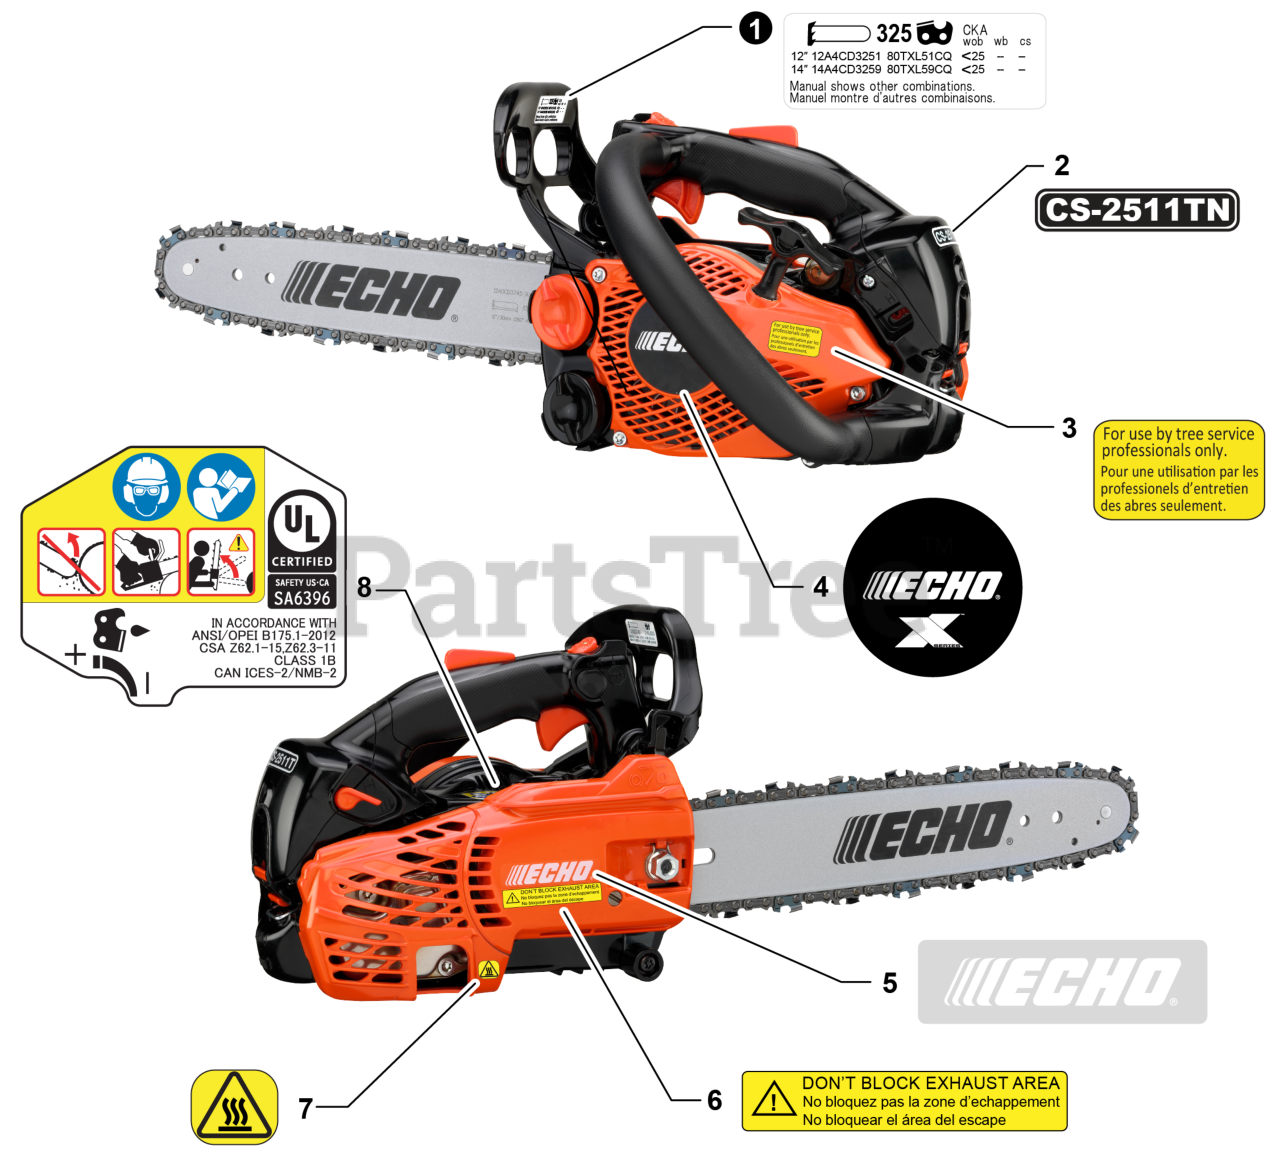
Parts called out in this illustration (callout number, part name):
1	LABEL - BAR & CHAIN
2	LABEL - CS-2511TN
3	LABEL - CAUTION - PROFESSIONALS ONLY
4	LABEL - ECHO
5	LABEL - ECHO
6	LABEL - CAUTION - DON'T BLOCK EXHAUST AREA
7	LABEL - CAUTION - HOT
8	LABEL - CAUTION
